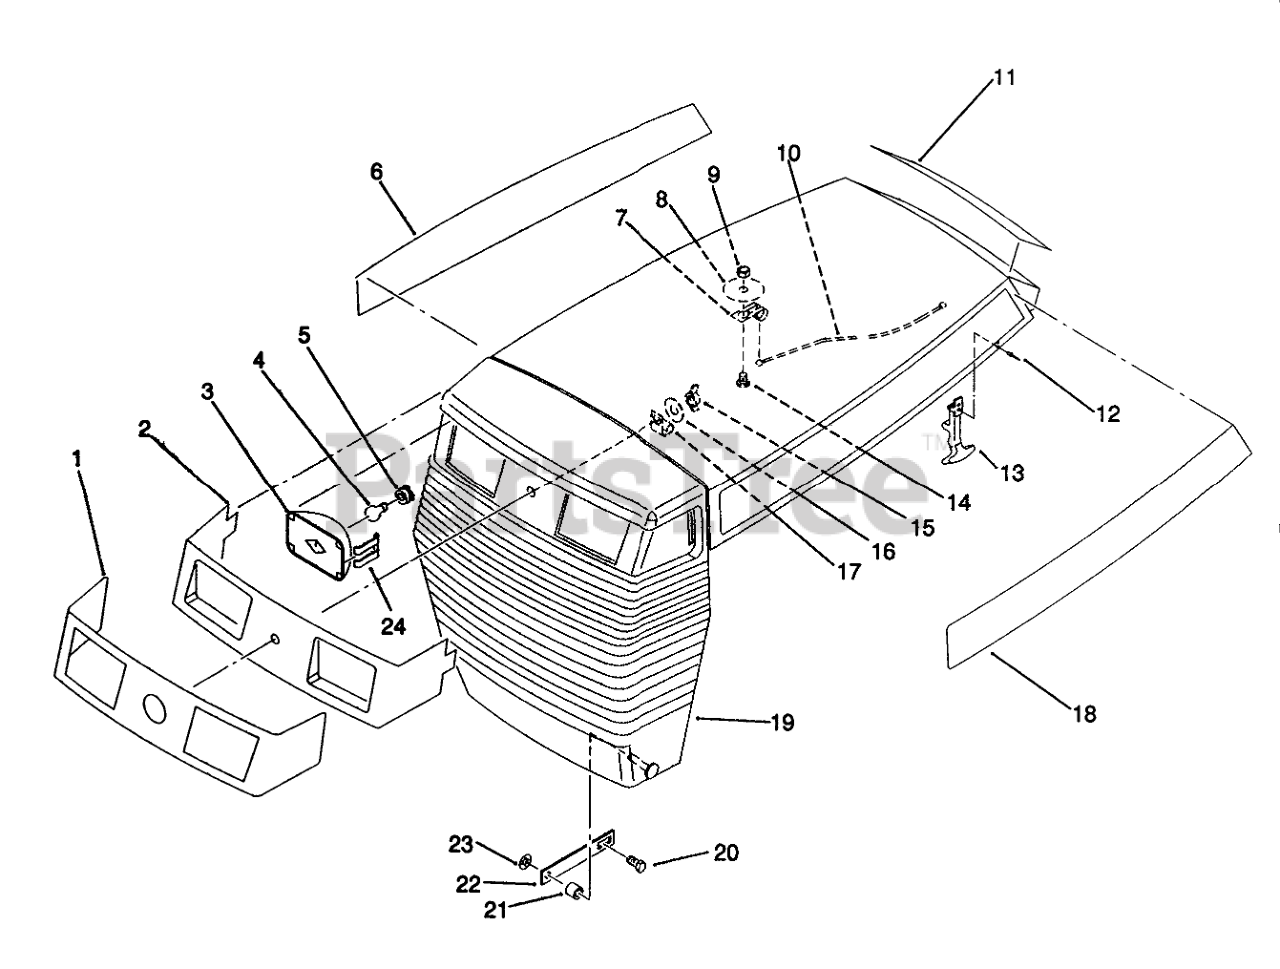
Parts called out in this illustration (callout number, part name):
1	DECAL-FRONT HOOD
2	LIGHT-BAR BLACK
3	LIGHT POD
4	BULB
5	SOCKET-HEADLIGHT
6	DECAL-HOOD R.H.
7	CLEVIS
8	WASHER-BACKING
9	Nut
10	CABLE-ASS'Y
11	Decal-Hood Rear
12	RIVET-POP
13	KEEPER-LATCH
14	Screw-HWH
15	Nut-Wing
16	WASHER
17	J-CLIP
18	DECAL-HOOD L.H.
19	Hood W.A.
20	Bolt
21	SPACER
22	STRAP R
23	PUSH-NUT 5/16
24	RETAINER
